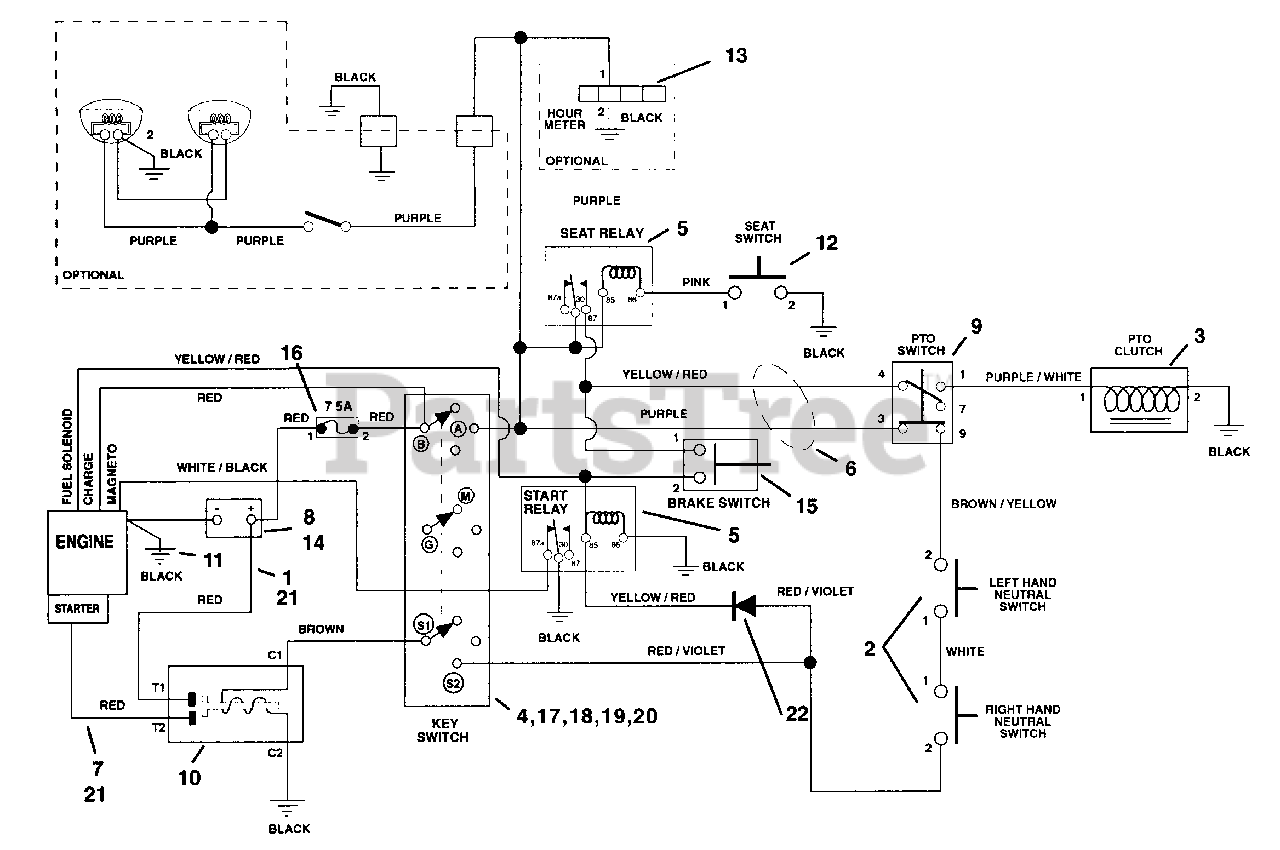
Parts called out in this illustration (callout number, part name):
1	CBL,BATTERY TO SOLENOID
2	SWITCH, NEUTRAL START N.O.
3	ELECTRIC CLUTCH/BRAKE(1.8AMP)
4	KEY SWITCH
5	RELAY
6	HARNESS, WIRE - 1440
7	STARTER CABLE 6.75"
8	BATTERY W/ TUBE
9	SWITCH, CLUTCH
10	SOLENOID
11	GROUND CABLE .31X22.00X.31
12	SWITCH- SEAT
13	HOUR METER
14	RUBBER PAD
15	SWITCH- SINGLE POLE N.O.
16	30 AMP Fuse
17	KEY -W/CAP
18	CAP - IGNITION SWITCH
19	NUT- PANEL .562-24 GRECO
20	WSHR-LK-INT .563X.040 PL
21	BOOT, INSULATOR
22	MOLDED DIODE PLUG 1 AMP
